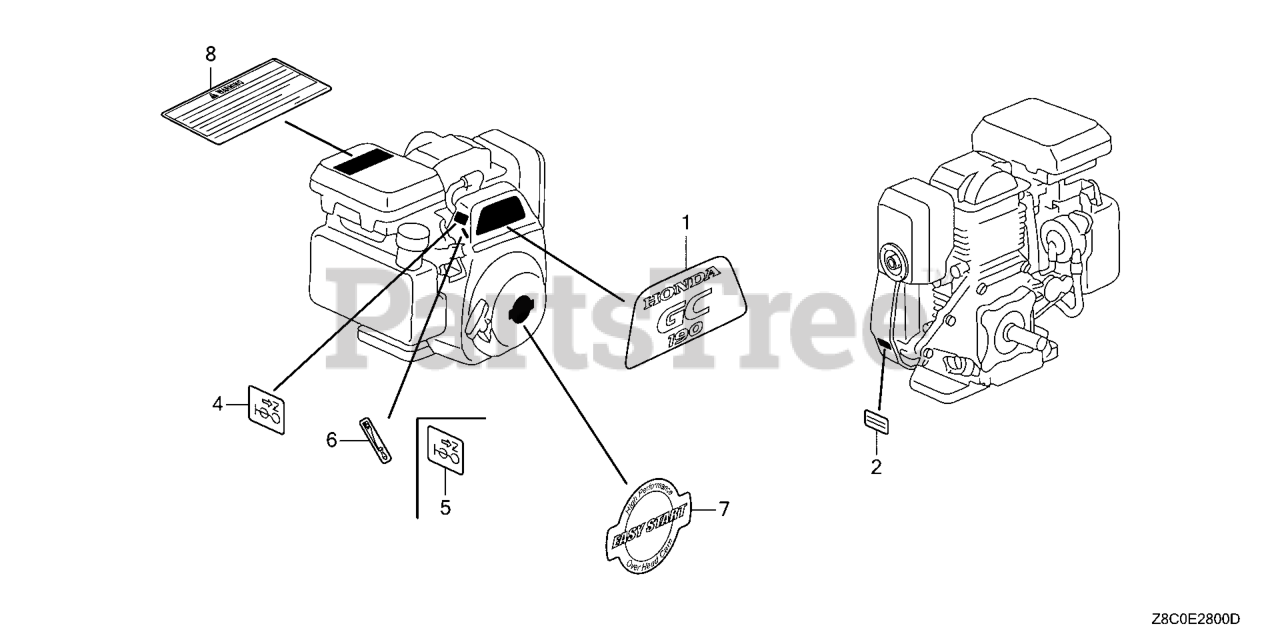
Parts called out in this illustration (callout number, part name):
1	MARK, EMBLEM (GC190)
2	LABEL, WARNING (NOT CERTIFIED FOR SALE)
5	MARK, CHOKE
7	MARK, RECOIL COVER
8	MARK, OPERATOR CAUTION (ENGLISH)
